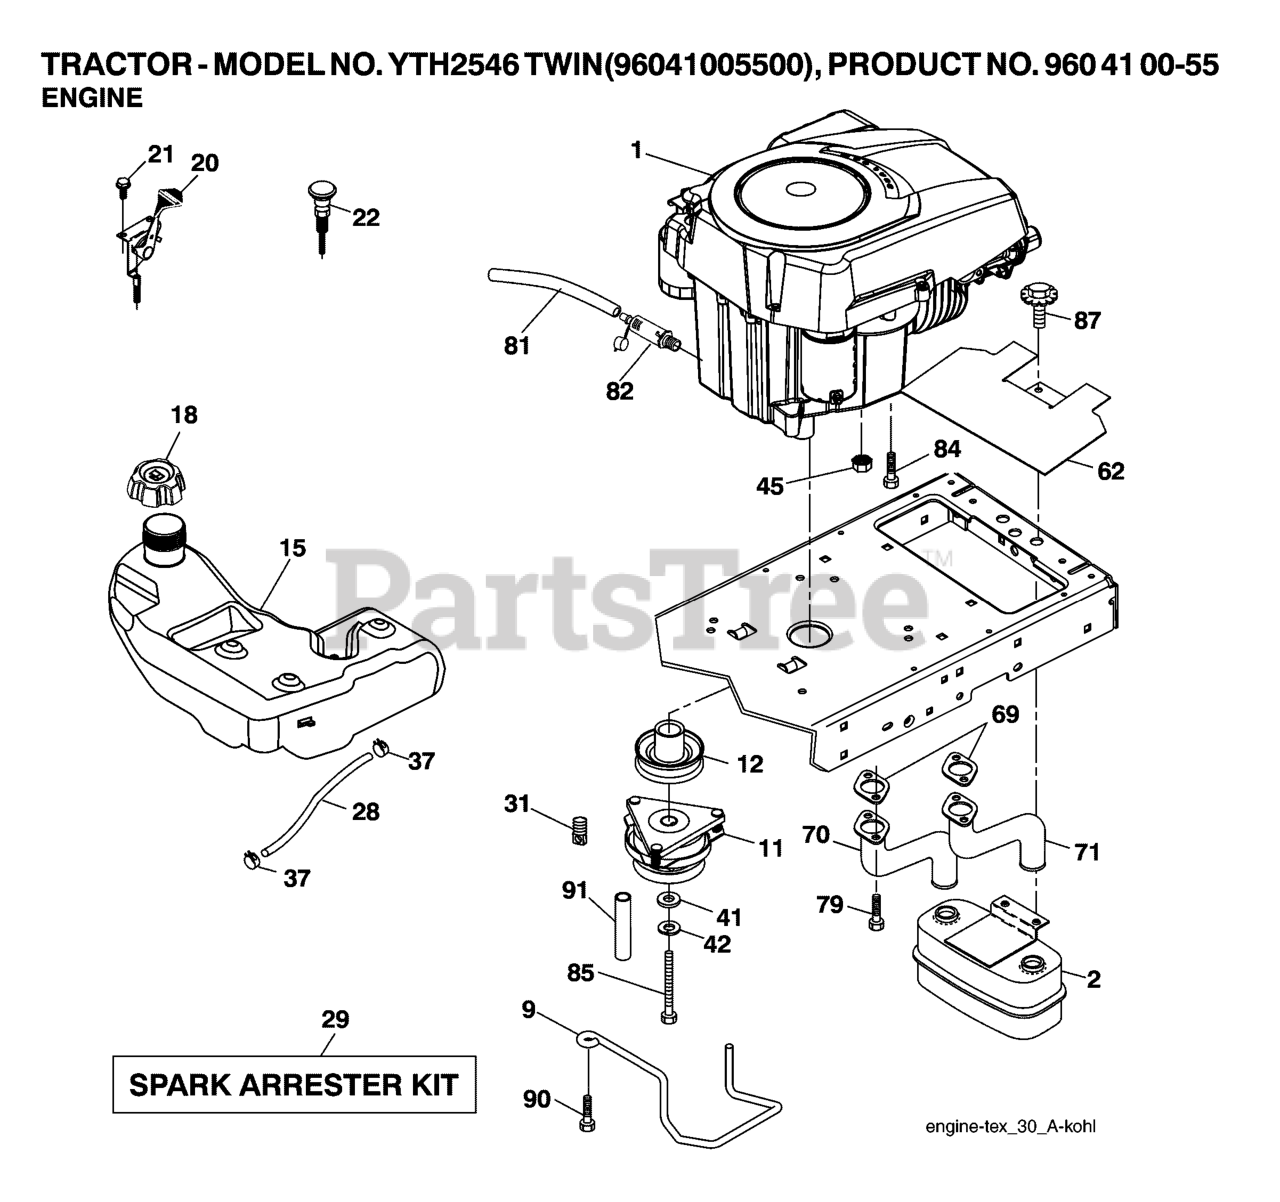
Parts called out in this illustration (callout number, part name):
2	MUFFLER.TWIN.CYL.LOW.TONE
9	KEEPER.BELT.ENGINE.4.2
11	CLUTCH ELECTRIC
12	PULLEY.ENGINE.TUFFTORQ
15	TANK.FUEL.4GAL
18	CAP.FUEL.TANK.3"GREY
20	THROTTLE CONTROL
21	SCREW
22	CONTROL.CHOKE.ERGO.PUSH-IN.BLA
28	REPL BY 532 00 85-43
29	KIT.SPARK ARRESTOR 794945 B&S
37	HOSE CLAMP
42	LOCKWASHER
45	NUT
62	RP SHIELD HEAT MUFFLER
69	GASKET.EXHAUST.KOHL.CV18-CV26
70	RP.PIPE-EXHAUST LH
71	RP.PIPE-EXHAUST RH
79	SCREW.SOCKET HD.5/16-1
81	TUBE, DRAIN OIL ASM.
82	PLUG DRAIN OIL EASY
84	SCREW 3/8-16X1
85	BOLT HEX
87	BOLT.5/16-18UNCX1.W/SEMS.BLK
90	SCREW 3/8-16X1
91	BUSHING.1.375OD
